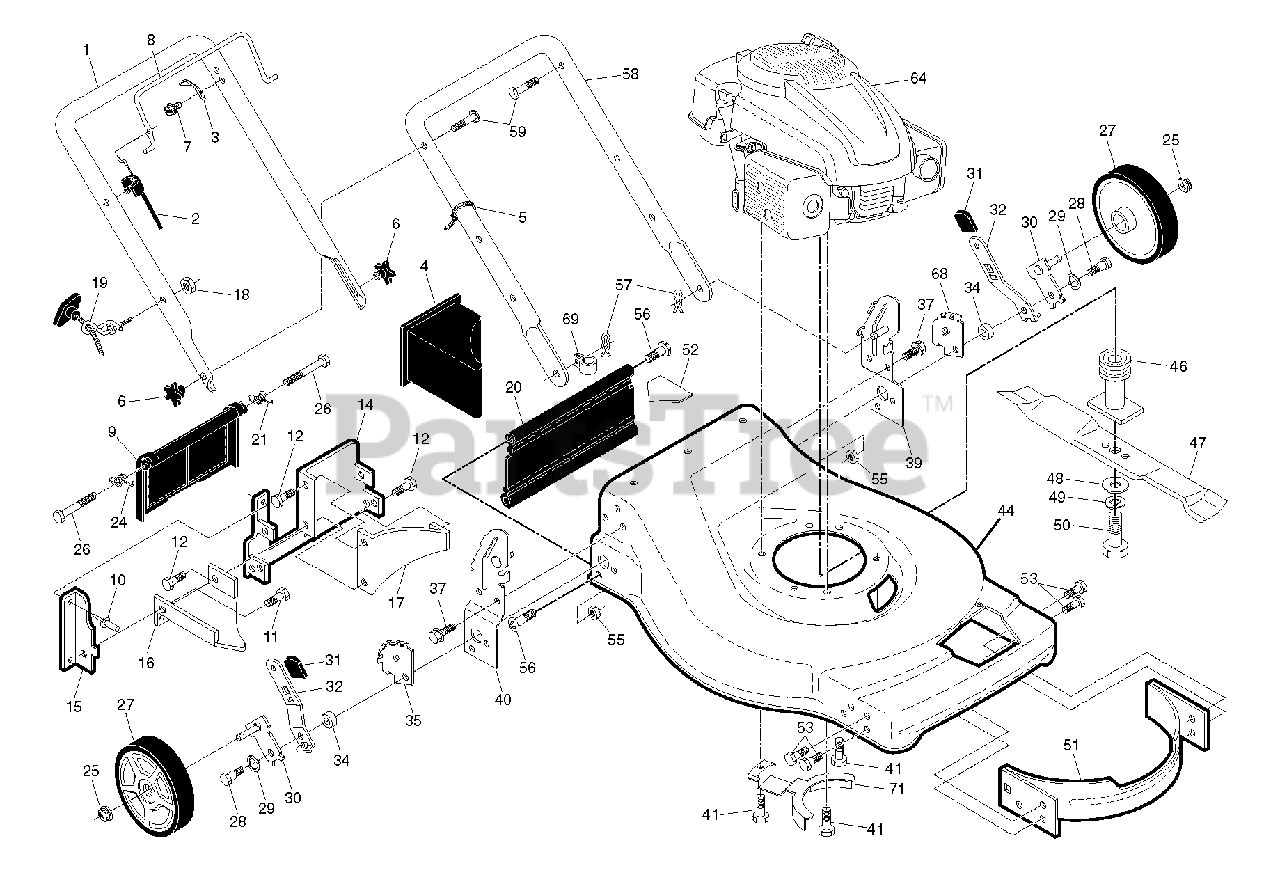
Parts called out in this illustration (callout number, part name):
1	HANDLE.UP.DSTR.FG/RGD.BLACK
2	CABLE.MZR
4	PLUG.MULCH.22RD
5	TIE GUIDE
6	KNOB.WING.PLASTIC.BLACK
8	BAIL.MZR.CURVED.YELLOW
9	REAR DOOR ASSY
10	RIVET BLIND
11	SCREW.HXTAP.10-24
12	SCREW 14-20 X 5/8
14	Back Plate
15	SIDE BAFFLE
16	DISCHARGE BAFFLE
17	REAR BAFFLE
18	NUT
19	GUIDE.ROPE.STD.BLK.ZIN
20	SKIRT.REAR.22RD/SD.FO/VE
21	SPRING.LH.22.REAR.DOOR.EZ.EMPT
24	SPRING.RH.22.REAR.DOOR.EZ.
25	NUT.HEX.FLANGE.3/8-16.LOCKNUT
28	BOLT SHOULDER 3/8 -16X1
29	WASHER.CURVED.CYLINDRICAL
30	AXLE ARM ASSY.
31	KNOB.ERGO.DLX.PLAS.MARI.MULTI
32	SELECTOR SPRING, FRONT
34	SPACER.HEIGHT.ADJUSTER
35	Wheel Adjusting Bracket
37	BOLT.HEX.HD.WASHER.5/16-18X.75
39	Handle Bracket Assembly, LH
40	Handle Bracket Assembly, RH
41	BOLT 3/8-16X1-1/8
46	ADAPTER.BLADE/PULLEY.25M
47	BLADE.22.MULCH.STANDARD
48	WASHER,HARDEN
50	SCREW, HEX HD 3/8-24 X 1-3/8
51	FRONT BAFFLE KIT
52	No Step Decal
53	SCREW 1/4X20
55	LOCKNUT
56	HINGE SCREW
57	HAIRPIN COTTER
58	HANDLE.LOWER.D-STRAIT.BLACK
59	BOLT, HANDLE 5/16-18X1.75
64	ENGINE.RATO.550S.140C
68	Wheel Adjusting Bracket, LH
69	CLIP.CABLE.BLK
71	BRACKET.ENG/BELTKEEPER.BZP
